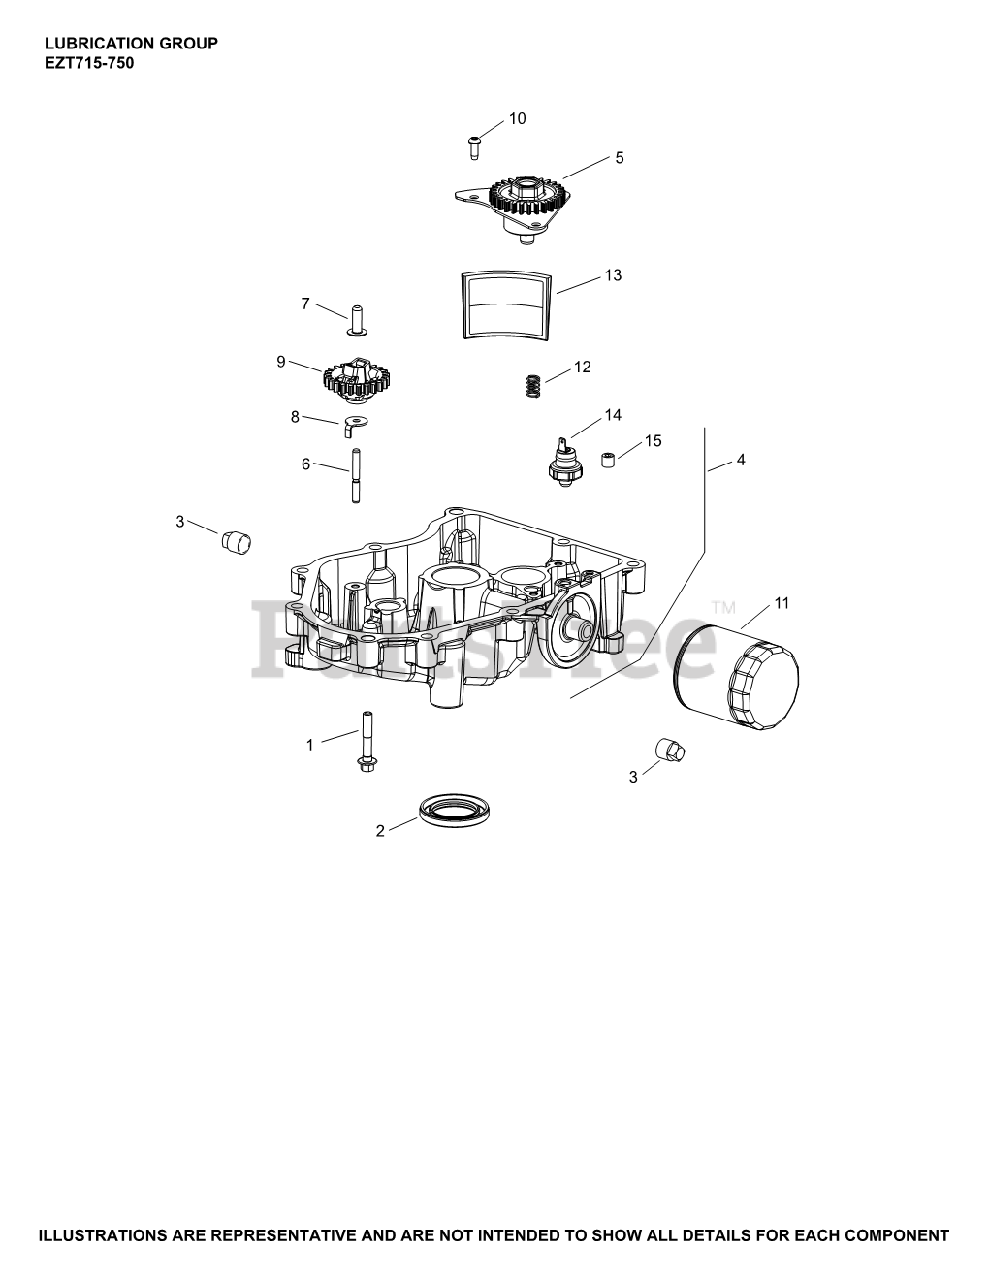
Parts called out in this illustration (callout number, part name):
1	SCREW, FLG M8X1.25X45
2	SEAL, OIL
3	PLUG, SQ HD PIPE 3/8"
4	PAN ASSEMBLY, OIL
5	PUMP ASSEMBLY, OIL
6	SHAFT, GOVERNOR GEAR
7	PIN, GOVERNOR REGULATING
8	TAB, LOCKING
9	KIT, GOVERNOR GEAR
10	SCREW, BUTTON HEAD
11	OIL FILTER
12	SPRING, COMPRESSION
13	SCREEN, OIL
14	SENSOR, OIL PSI
